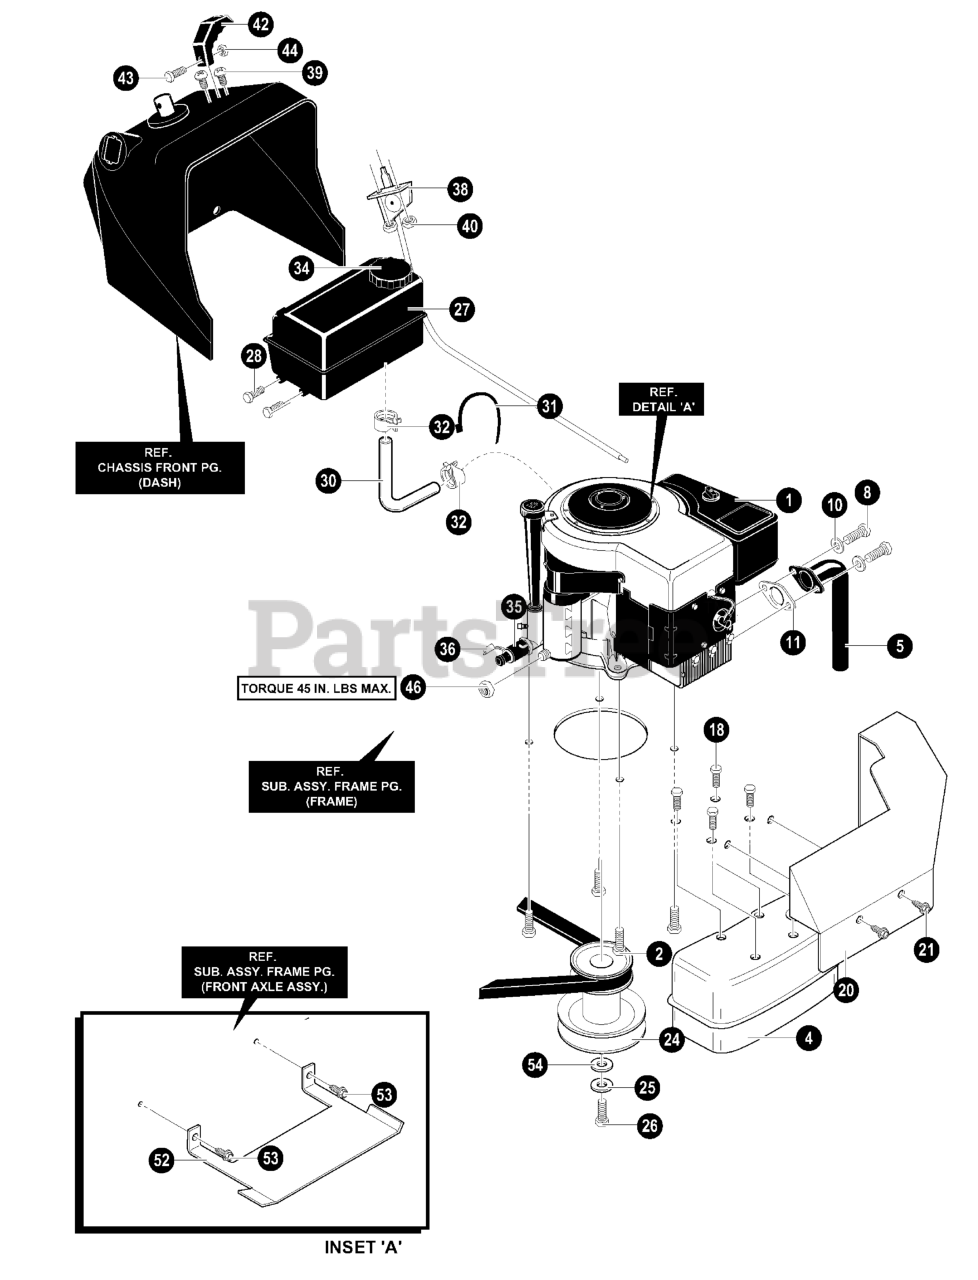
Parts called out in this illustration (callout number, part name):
1	13HP
2	SCREW, 3/8-16 x 1.25
4	MUFFLER, SUPER LOW
5	EXHAUST PIPE
8	SCREW, 5/16-18 x 0.75P
10	WASHER, HVSPTLK .328 x .
11	GASKET, Exhaust
18	SCREW, 1/4-20X.63 HHWATAP
20	HEAT SHIELD ASSY.
21	SCREW, 5/16-18 x 0.75 HHWATAP
24	STACK PULLEY ASSY.
25	WASHER, REGSPTLK .459X.
26	SCREW, 7/16-20 NF1.50HH
27	TANK, FUEL 1.5 GAL W/O SENSOR
28	SCREW, 15TPIX. PAN
30	GAS LINE
31	CABLE TIE
32	CLAMP, FUEL CLAMP
34	GAS CAP 2.5 THROAT
35	OIL DRAIN VALVE ASSEMBLY
36	CAP, OIL DRAIN VALVE
38	THROTTLE CONTROL
39	SCREW, 10-24X.63 PHPNMA
40	NUT, #10-24 HXHDNYLK
42	KNOB, THROTTLE CONTROL
43	SCREW, #8-32X.38 PHPN
44	NUT, #8-32 REGHX
46	NUT, 1/4-20 REGHXJAM
52	SHIELD, ANTI-DEHYDRATION
53	SCREW, 5/16-18 x 0.75 HHWATAP
54	WASHER, FLAT .480X1.
